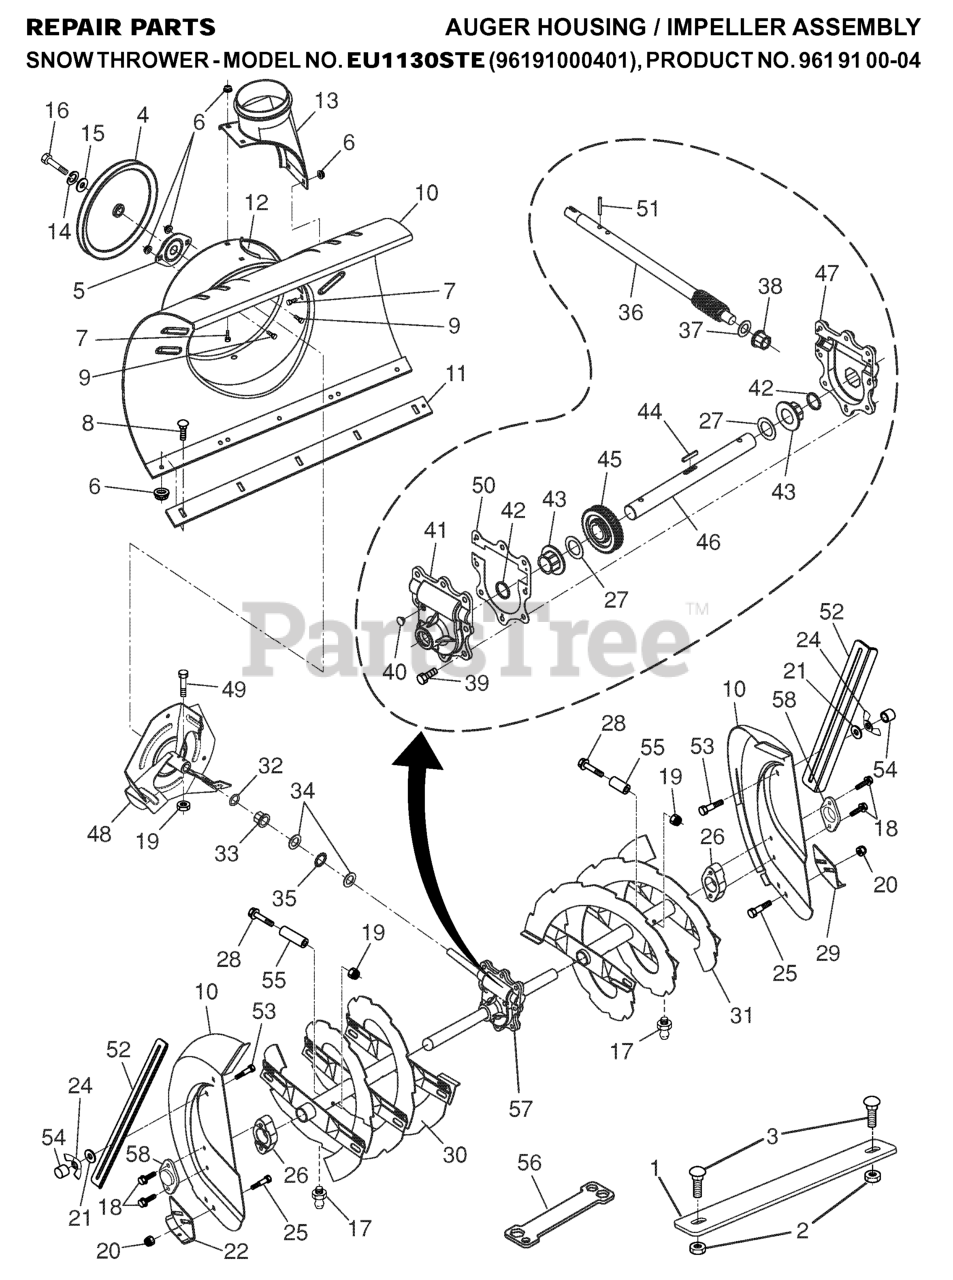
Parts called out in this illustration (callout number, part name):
1	WEIGHT AUGER HOUSING 30
2	NUT.LOCK.5/16-18
3	BOLT.CARRIAGE.5/16-18
4	PULLEY, IMPELLER
5	BEARING FLANGE
6	NUT, HEX FLANGE 5/16-18
7	BOLT.CARRIAGE.5/16-18X
8	BOLT
10	HOUSING, AUGER
11	BAR, SCRAPER
12	BRACKET, CORNER DISCHARGE
13	BASE DISCHARGE CHUTE
14	WASHER, FLAT
15	WASHER, LOCK 5/16
16	Screw, Hex Head 5/16-18 x 3/4
17	GREASE FITTING
18	SCREW, HEX HD 5/16X1
19	LOCKNUT.NYLOC.1/4-20
20	NUT, HEX FLANGE 5/16-18
22	SKID PLATE RH
24	NUT WING PM
25	BOLT
26	BEARING.BALL.AUGER.SHAFT
27	WASHER TRUST 1"
28	BOLT, SHEAR
29	SKID PLATE LH
30	AUGER ASSEMBLY, RH
31	AUGER ASSEMBLY, LH
33	BUSHING, FLANGE 3/4
34	WASHER, THRUST 3/4
35	BEARING TRUST 3/4 NTA-1220
36	SHAFT, IMPELLER
37	WASHER, THRUST 5/8
38	FLANGE BUSHING-5/8
39	HEX SCREW-5/16 X 3/4
40	CASE PLUG
41	GEARBOX HOUSING-RH
42	OIL SEAL
43	FLANGE BUSHING-1"
44	KEY, SQUARE 1/4 X .875
45	WORM GEAR
46	AUGER SHAFT
47	HOUSING.GEARBOX.LH(SERVICE)
48	IMPELLER ASSY
49	SCREW.HEX.HD1/4-20X
50	GEARBOX GASKET
51	PIN, ROLL 3/16 X 1-1/8
52	BAR, DRIFT
53	BOLT, HEX HEAD
54	STOP.11261.PLASTIC.30X50L.RED
55	SPACER.3943.SLEEVE.250X.47
56	RP WRENCH, SNOWTHROWER
57	GEARBOX.ASSEMBLY.AUGER
58	BEARING RETAINER, PLASTIC
